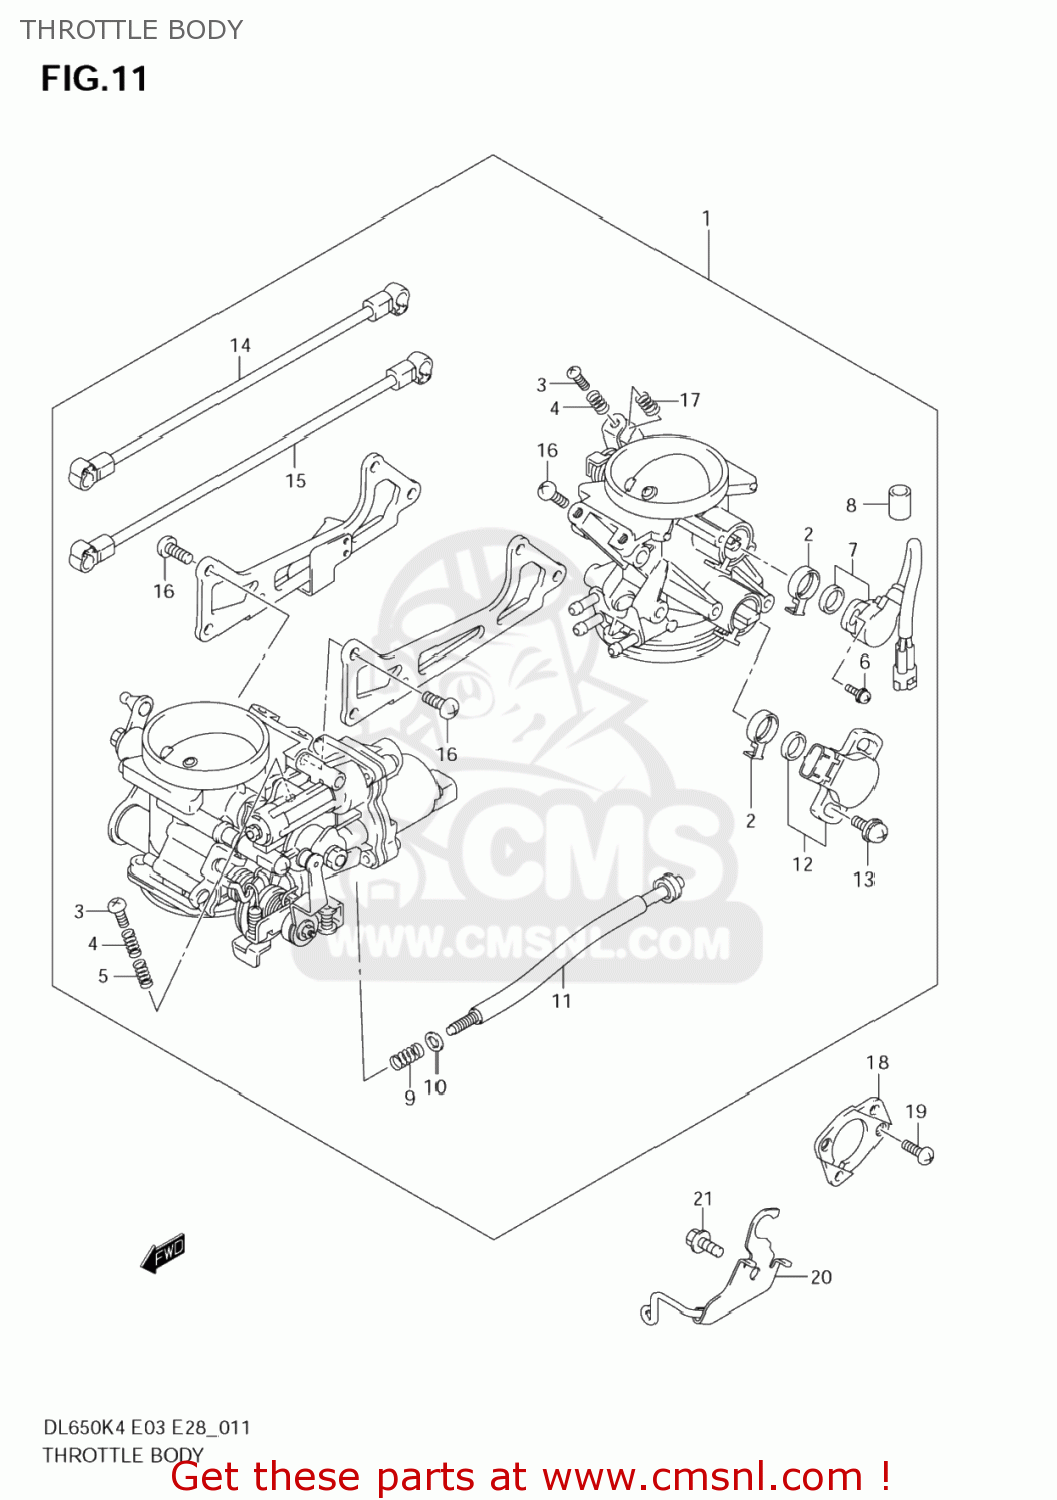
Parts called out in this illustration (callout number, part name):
1	THROTTLE BODY
2	RING
3	SCREW
4	SPRING
5	SPRING,THROTTLE SCREW
6	SCREW
7	SENSOR ASSY
8	HOSE
9	SPRING
10	WASHER
11	SCREW ASSY,ADJUST
12	SENSOR ASSY,THROTTLE
13	SCREW
14	ROD ASSY
15	ROD ASSY
16	SCREW
17	SPRING
18	PLATE
19	SCREW
20	BRACKET,IDLE ADJUST
21	BOLT
